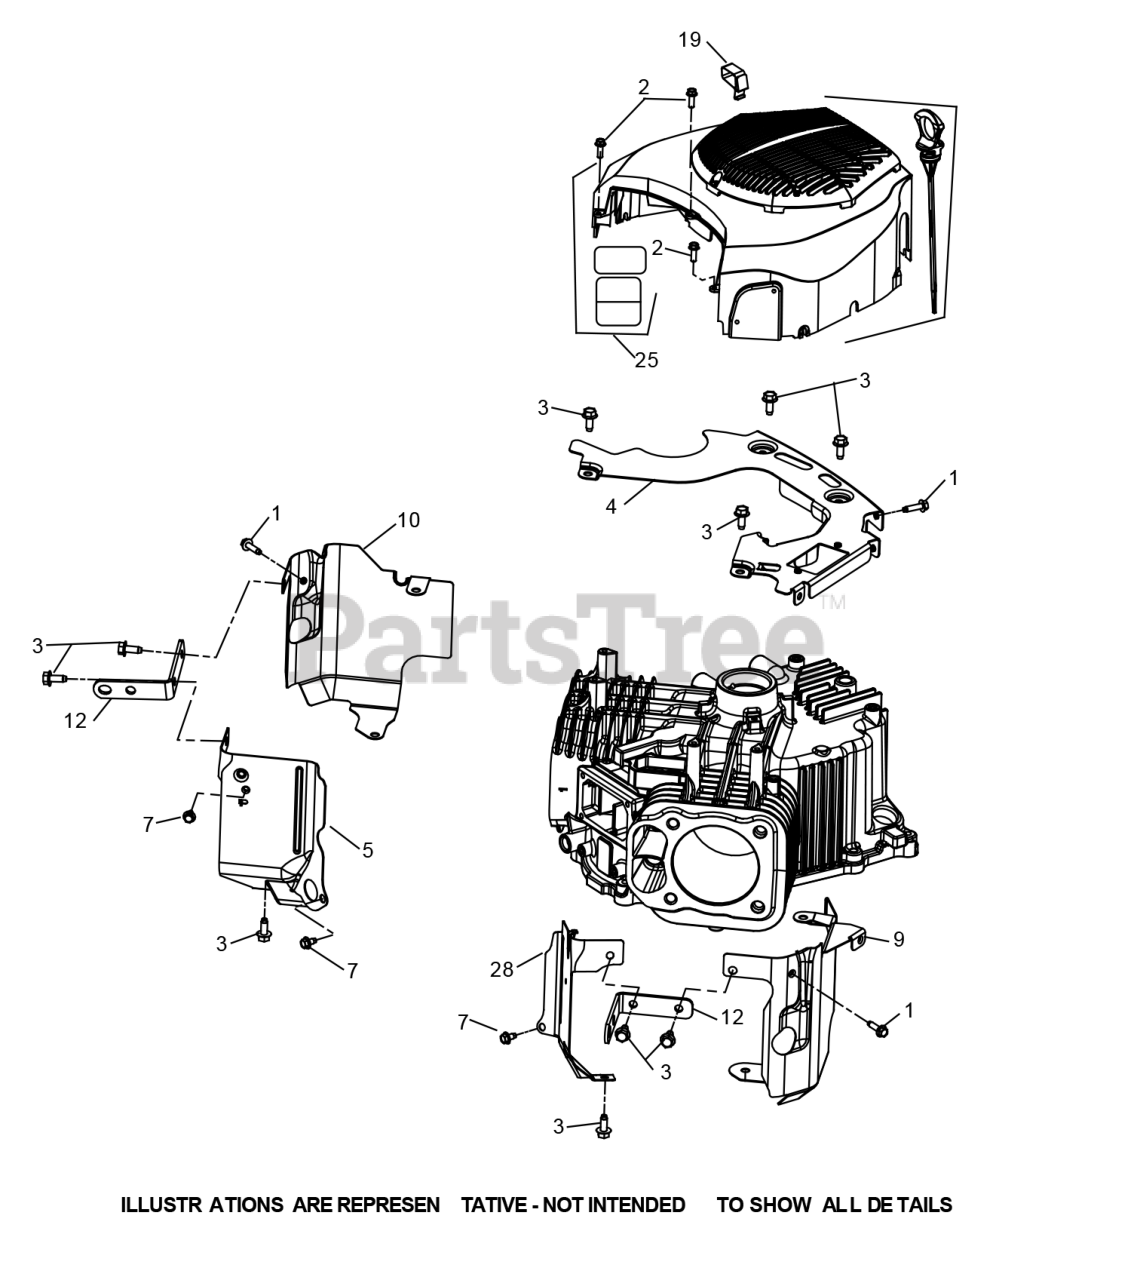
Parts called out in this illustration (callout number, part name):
1	THREAD FORMING SCREW
3	SCREW-THREAD FORMI
4	PLATE-BACKING
5	VALLEY BAFFLE-# 1
9	BAFFLE-LEFT BARREL
10	BAFFLE-RIGHT BARRE
12	STRAP-LIFTING
19	BLOWER HOUSING CLIP
25	BLOWER HOUSING KIT
28	VALLEY BAFFLE #2
